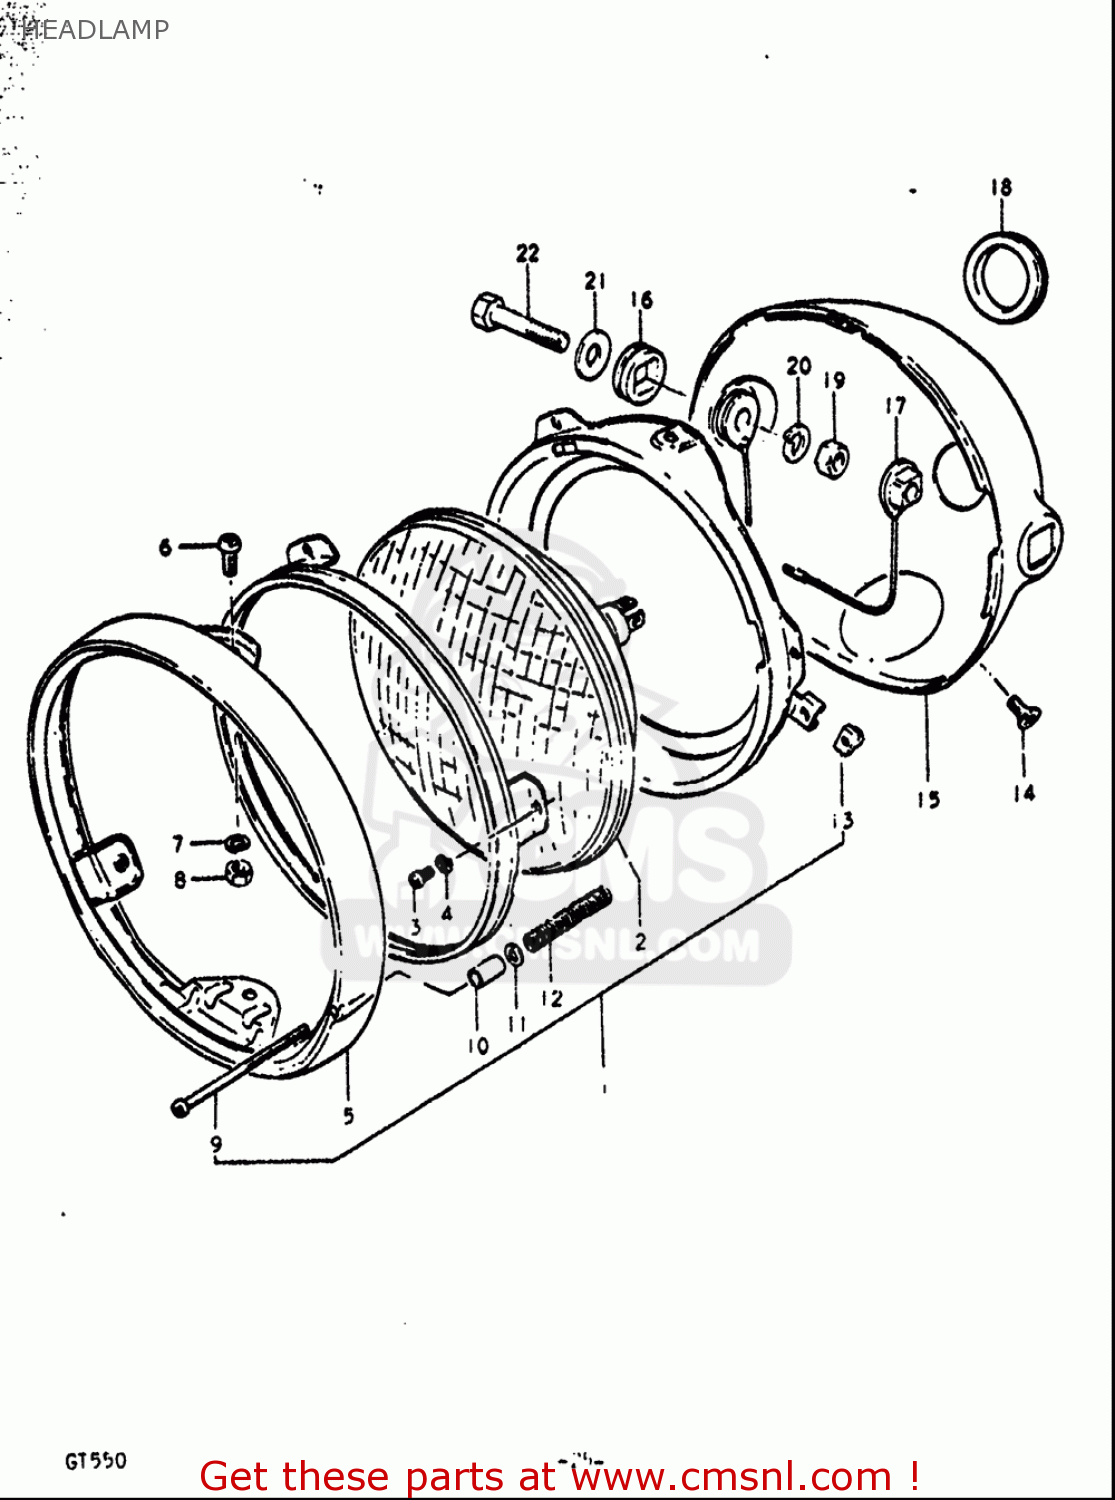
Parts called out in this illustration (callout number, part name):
3	SCREW
4	WASHER,LOCK
5	RIM,HEADLAMP
6	SCREW
7	WASHER,LOCK
8	NUT
9	SCREW
11	WASHER
13	NUT
14	SCREW
15	HOUSING,HEADLAMP
16	CUSHION,HOUSING
17	PIECE,ADJUSTER
18	GROMMET,HEADLAMP HOUSING
19	NUT
20	WASHER,LOCK
21	WASHER
22	BOLT
